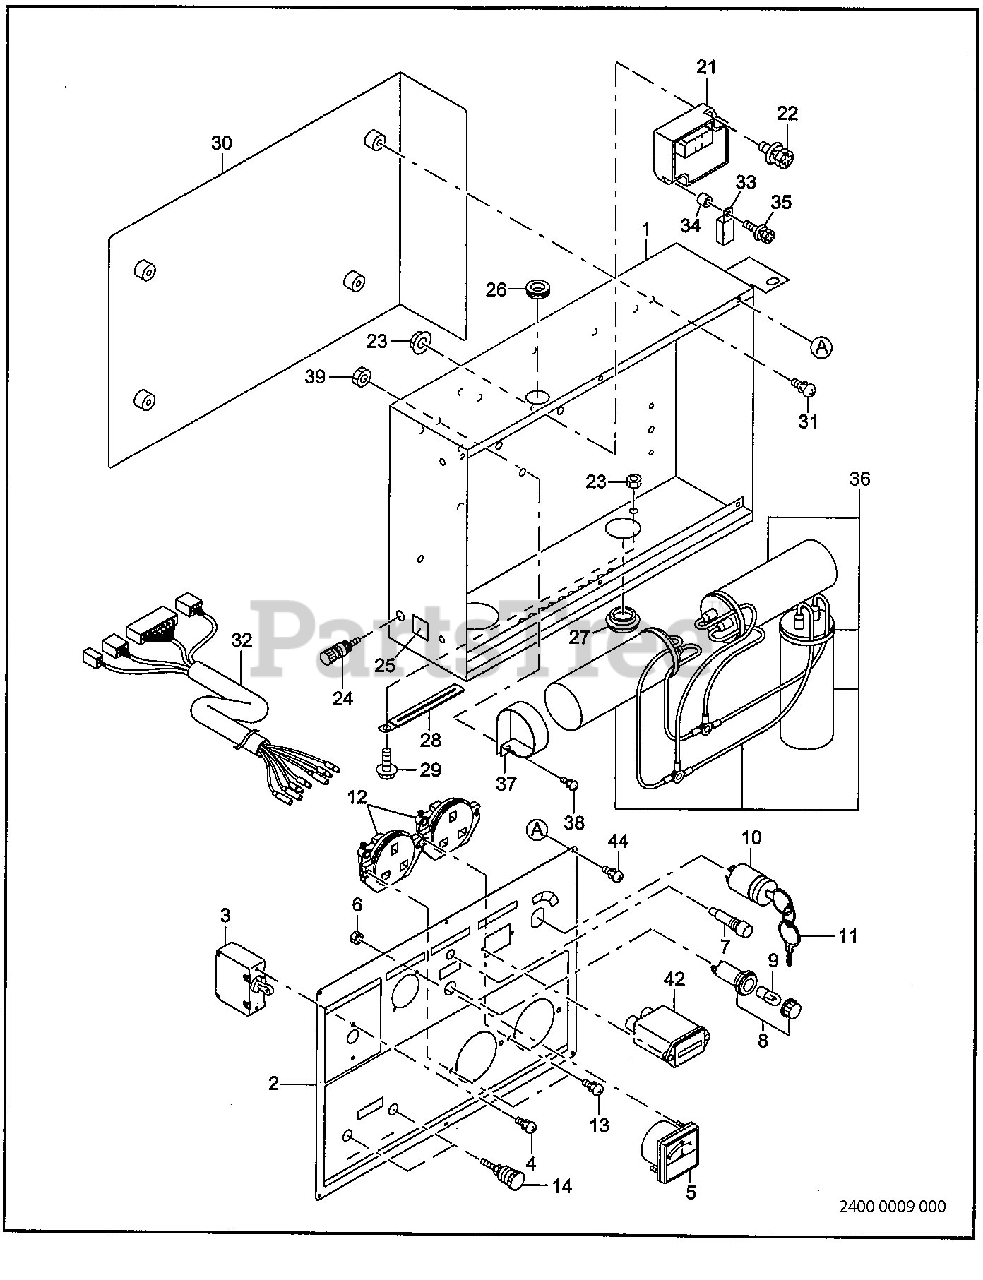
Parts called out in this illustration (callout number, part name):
1	CONTROL BOX ASSY
1	CONTROL BOX UNIT
2	CONTROL BOX ASSY
2	CONTROL PANEL
3	NO FUSE BREAKER (1P-30A)
4	SCREW and WASHER ASSY
8	LAMP (OIL)
9	LAMP (18V-0.11A)
10	KEY SWITCH
12	AC RECEPTACLE (250V-13A)
13	SCREW and WASHER ASSY
14	TERMINAL
21	ECU (O/S & R/C) ASSY
22	SCREW and WASHER ASS
22	SCREW and WASHER ASSY
23	FLANGE NUT
26	GROMMET
29	FLANGE BOLT
31	SCREW and WASHER ASSY
32	WIRE ASSY
35	SCREW
36	CONDENSER ASSY (371JFX3)
37	CONDENSER BRACKET
38	SCREW and WASHER ASSY
44	SCREW and WASHER ASSY
